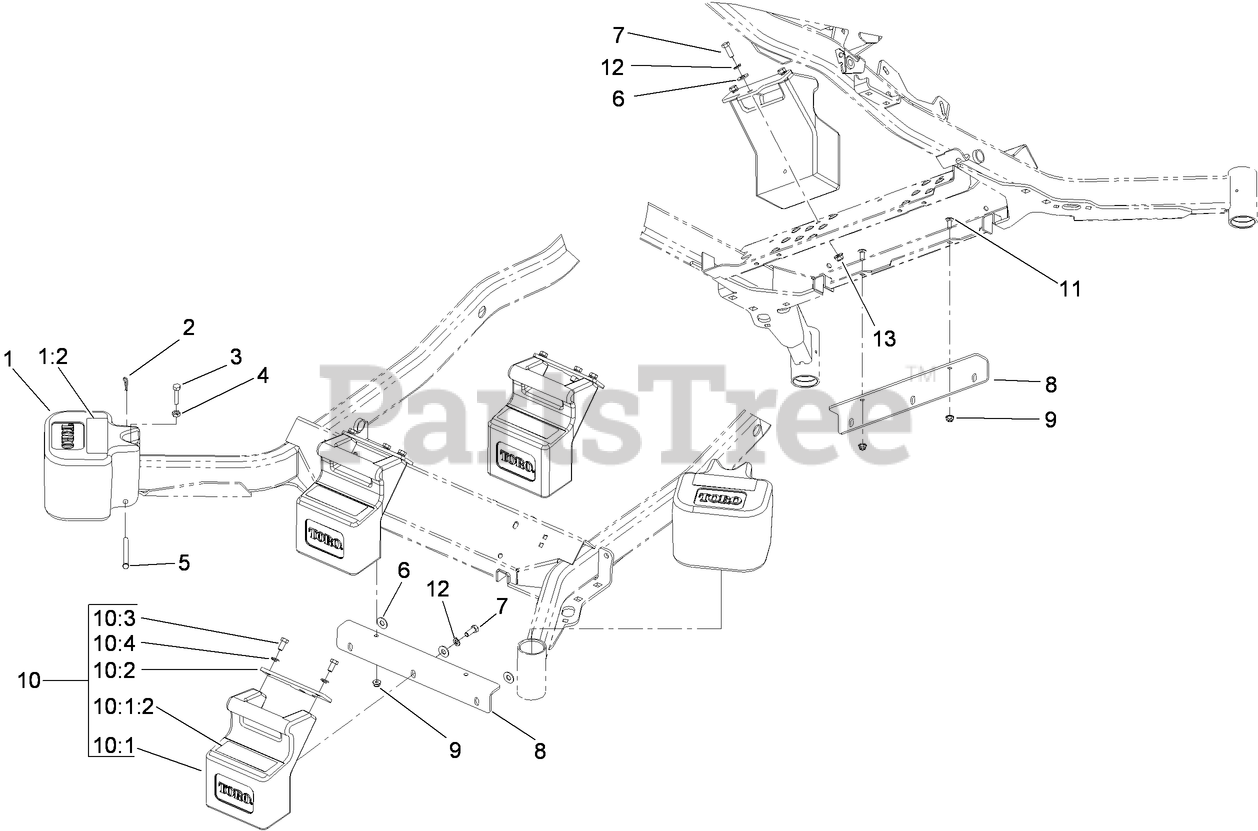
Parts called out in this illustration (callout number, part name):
1	63 LBS WEIGHT ASM
1:2	Decal-Warning, Counterweight
2	PIN-COTTER
3	BOLT-HH
4	NUT-HEX
5	PIN-CLEVIS
6	WASHER-FLAT
7	SCREW-HH
8	BRACKET-MOUNT, WEIGHT
9	NUT-HF, NI
10	WEIGHT ASM
10:1	OBS WEIGHT
10:1:2	Decal-Warning, Counterweight
10:2	TAB-SUPPORT, WEIGHT
10:3	SCREW-HH
10:4	WASHER-LOCK
11	SCREW-CARR
12	WASHER-LOCK
13	NUT-HF, NI
